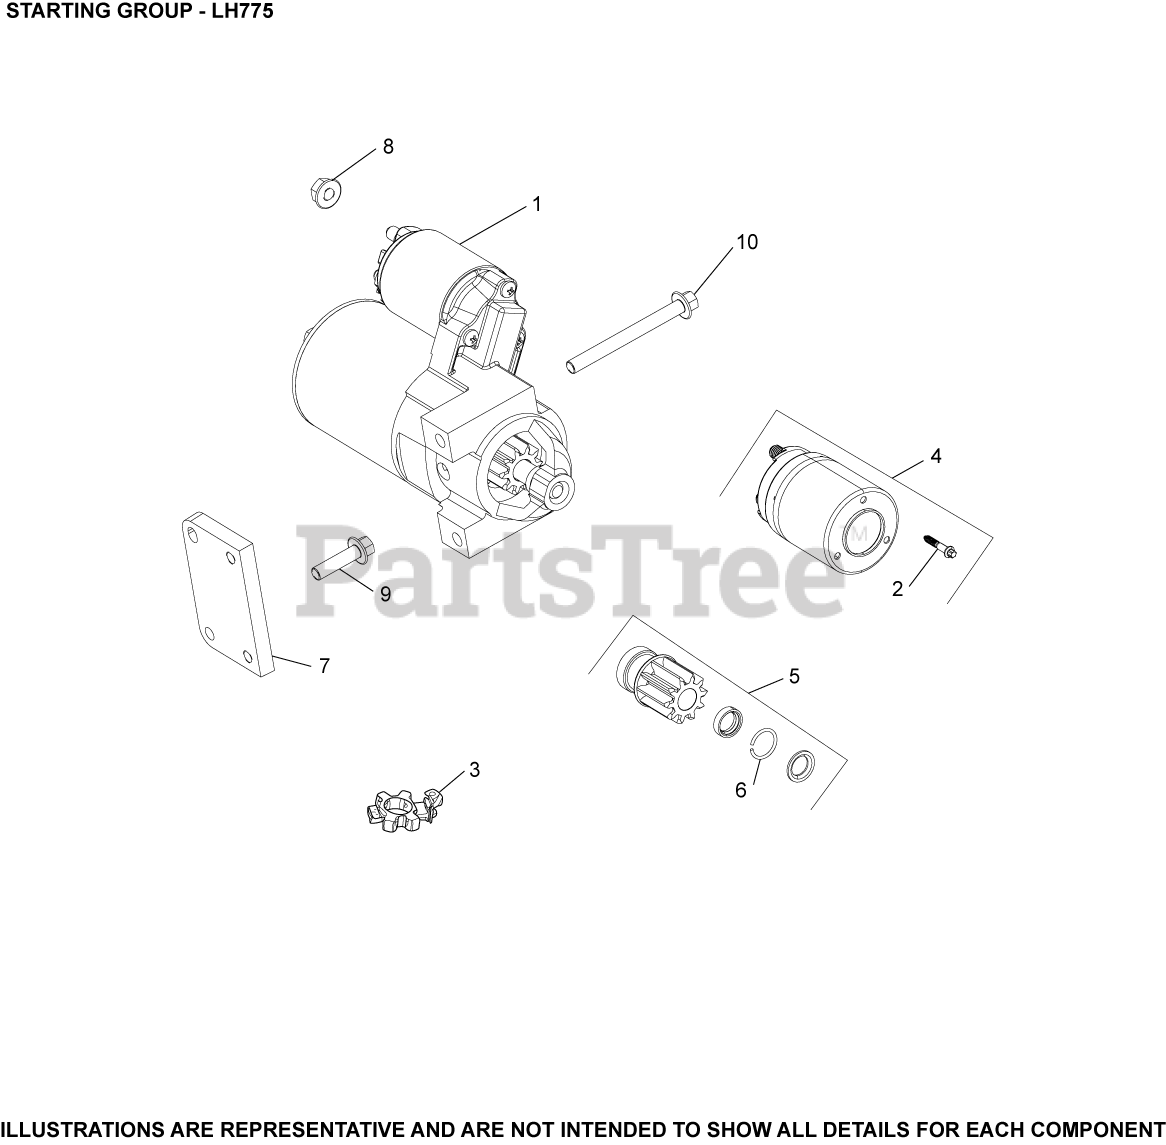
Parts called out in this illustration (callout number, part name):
1	STARTER, SOLENOID SHIFT-USE 25 098 11-S
2	SCREW, EXTERNAL TORX HEAD
3	KIT, BRUSH HOLDER
4	KIT, SOLENOID
5	KIT, STARTER PINION
6	RING, RETAINING
7	PLATE, STARTER - USE 66 146 54-S
8	NUT, FLG M8X1.25
9	SCREW, FLG M8X1.25X30
10	SCREW - USE M-851080-S
